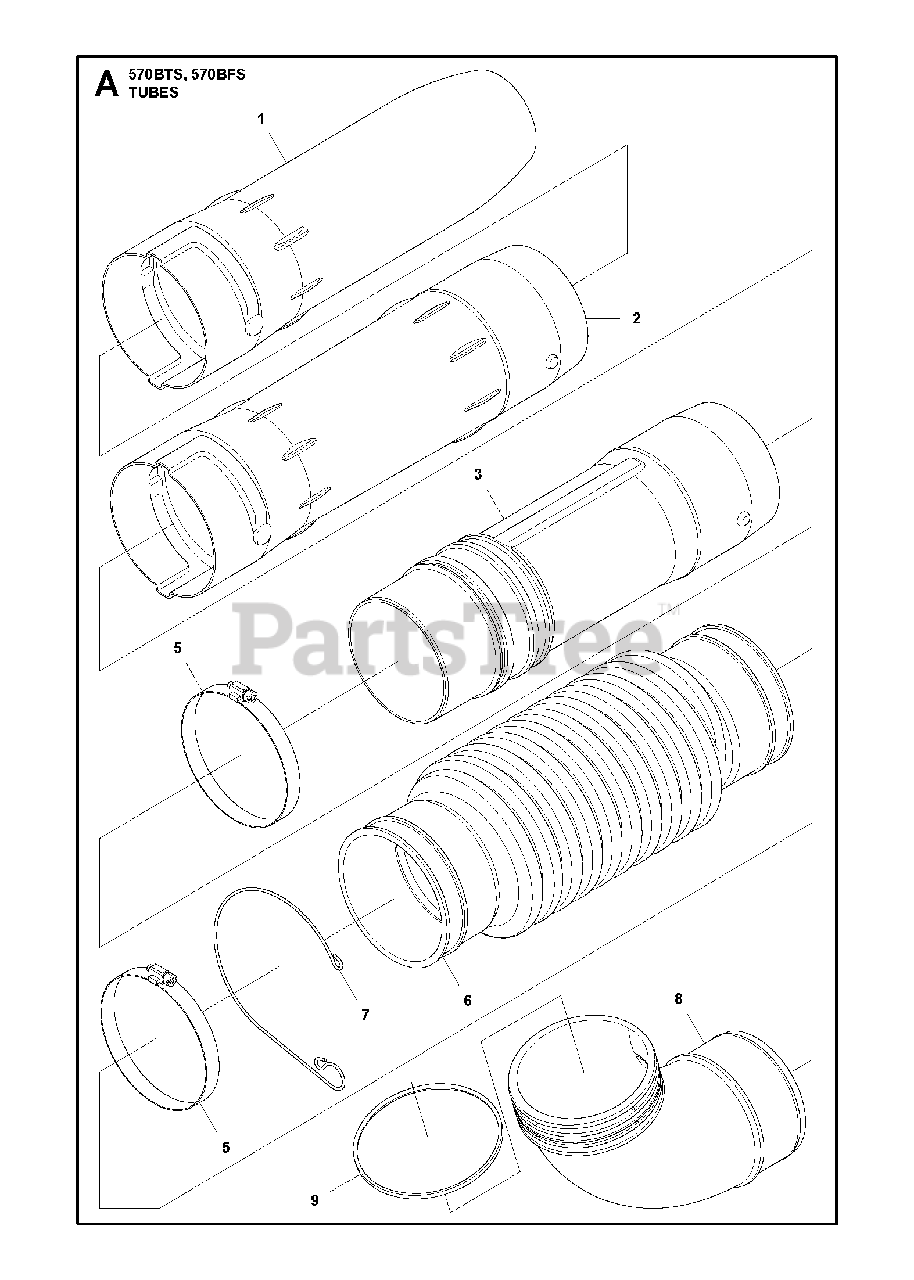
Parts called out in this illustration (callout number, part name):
2	PIPE STRAIGHT
3	SWIVEL JOINT
5	CLAMP(F115)
6	HOSE
8	PIPE ELBOW
